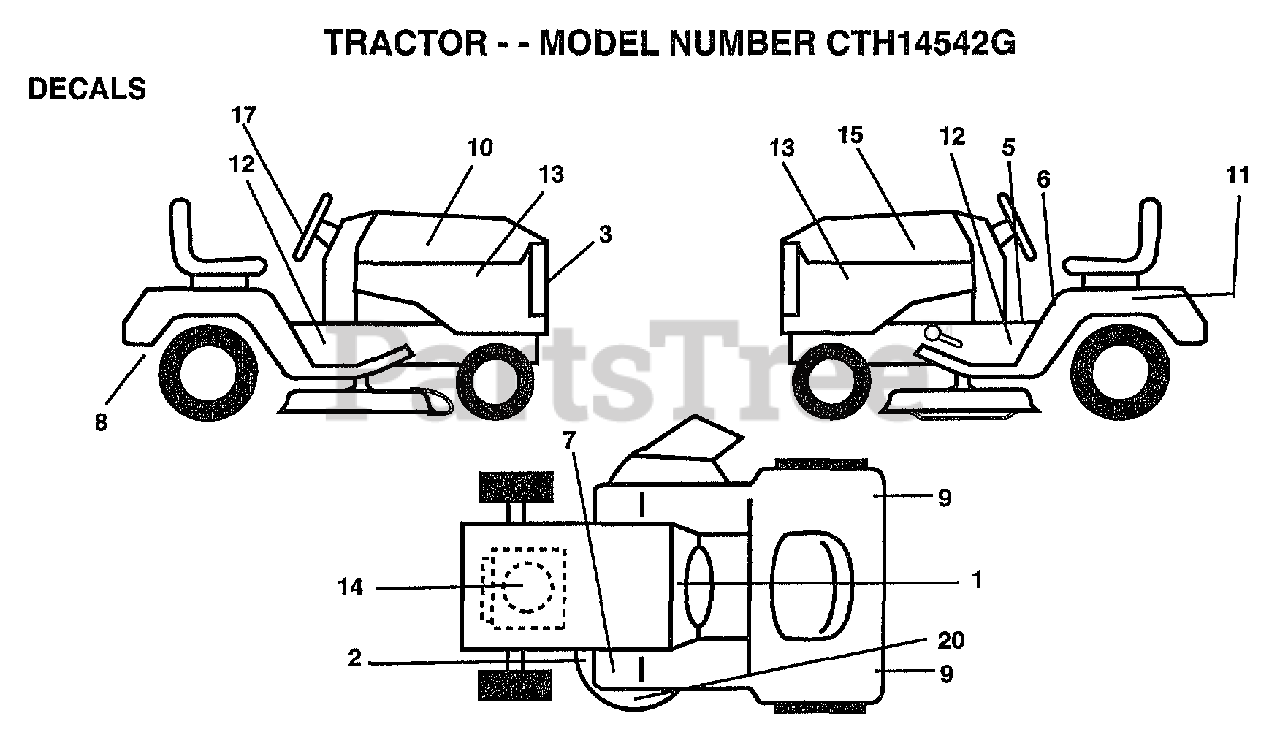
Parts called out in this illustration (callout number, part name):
1	"DECAL-INST,OPER"
2	"DECAL-SCHEM,BELT"
3	DECAL GRILLE
5	DECAL BRAK PARK
6	"DECAL DANGER,FEND"
8	DECAL DRAWBAR LH
9	REFLECTOR-TAIL YT
10	DECAL HOOD RH
11	DECAL.BATRY.3-3908
12	"DECAL CHASSIS 42"""
13	DECAL SIDE PANEL
14	DECAL, ENGINE
15	DECAL HOOD LH
17	DECAL INST STG WH
20	"DECAL,ENVIRO DECK"
